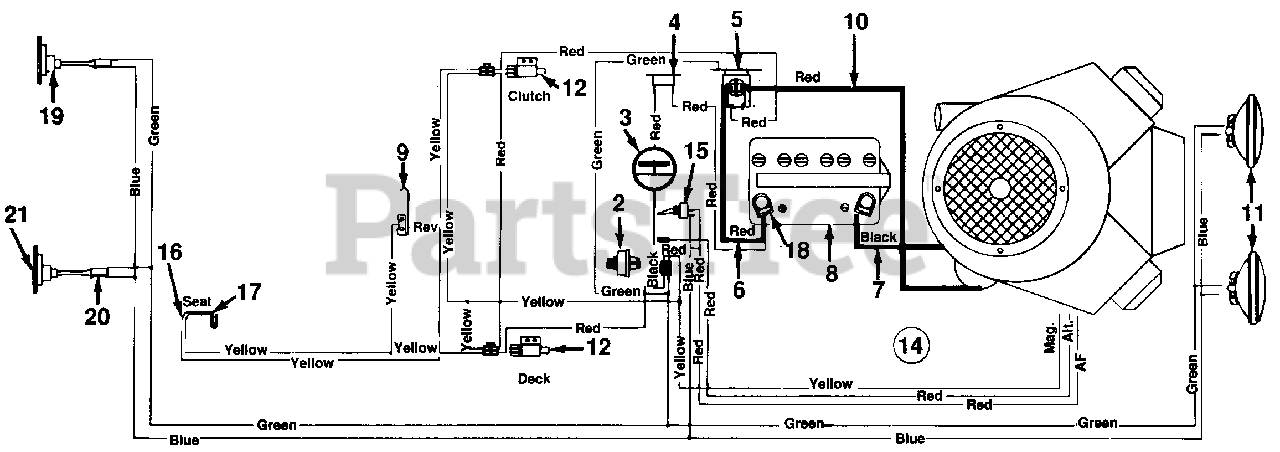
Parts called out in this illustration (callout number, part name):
2	Ignition Switch
3	Ammeter
4	Circuit Breaker 20 Amp
5	Solenoid
6	Electric Wire
7	Electric Wire
8	Battery
9	Spring Switch (Reverse Safety)
10	Electric Wire
11	Headlights
12	Safety Switch (PTO & Clutch)
14	Wire Harness (Vanguard)
15	Light Switch
16	Safety Switch (Seat)
17	Safety Switch (Seat)
18	Battery Boot
19	Taillight
20	Taillight Harness
21	Taillight Bulb
